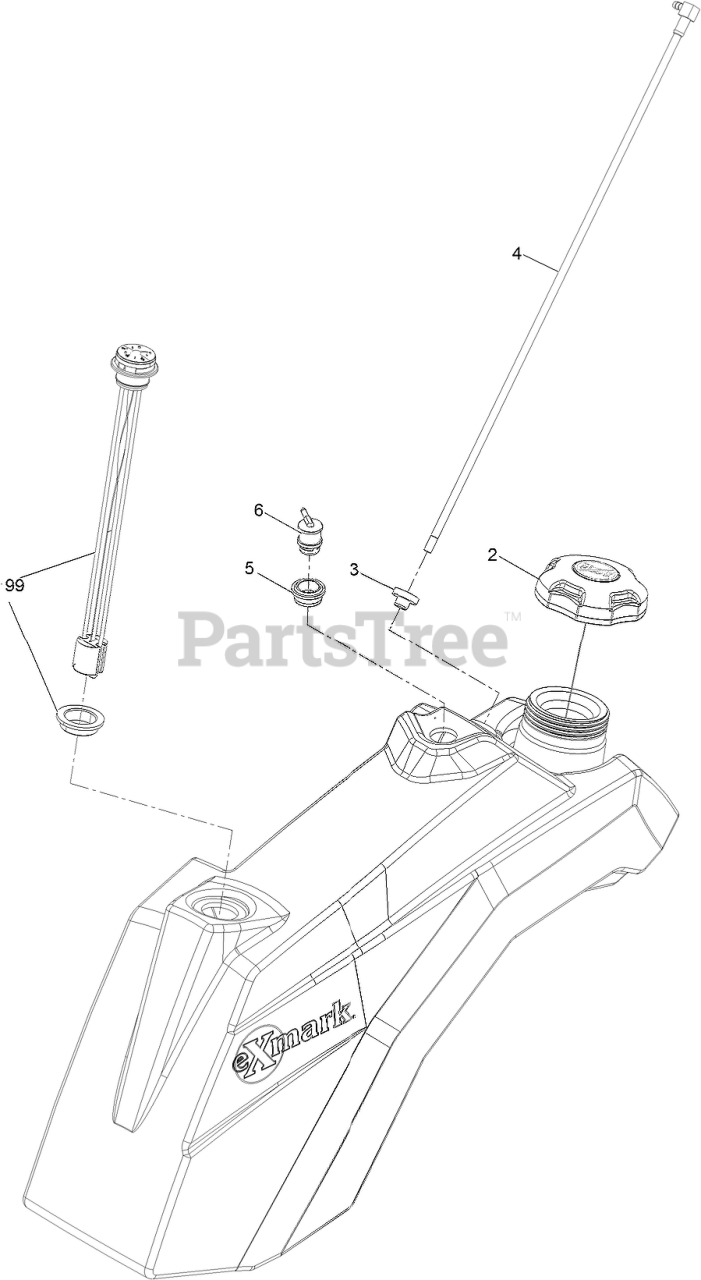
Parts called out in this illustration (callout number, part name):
2	CAP-FUEL, RATCHETING
3	BUSHING
4	STRAW, FUEL, LONG
5	GROMMET
6	VALVE-VENT, FUEL
99	KIT-FUEL GAUGE REPLACEMENT
